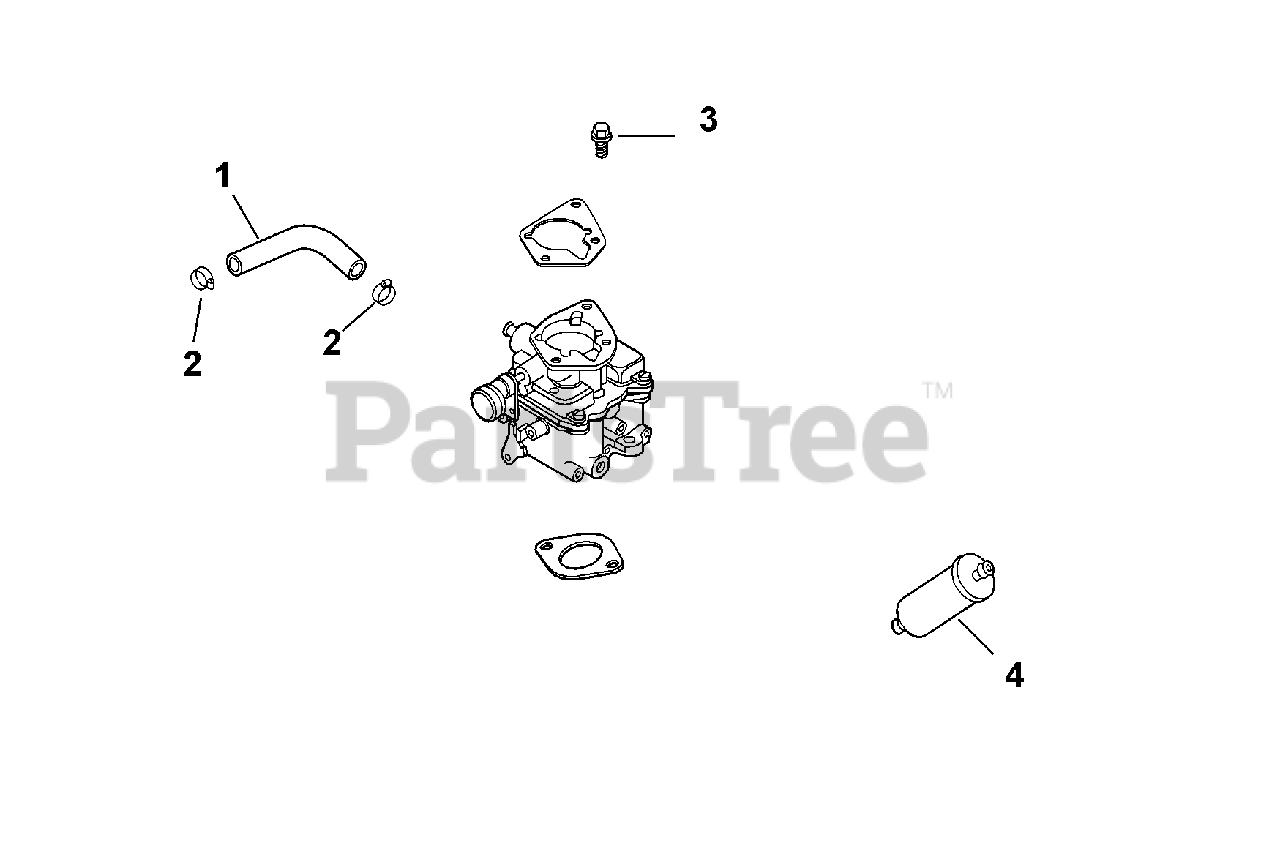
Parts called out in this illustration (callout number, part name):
1	Line, fuel 24" - cut to length (2)
3	Screw, Flg M6X1.0X25
4	Fuel Filter
